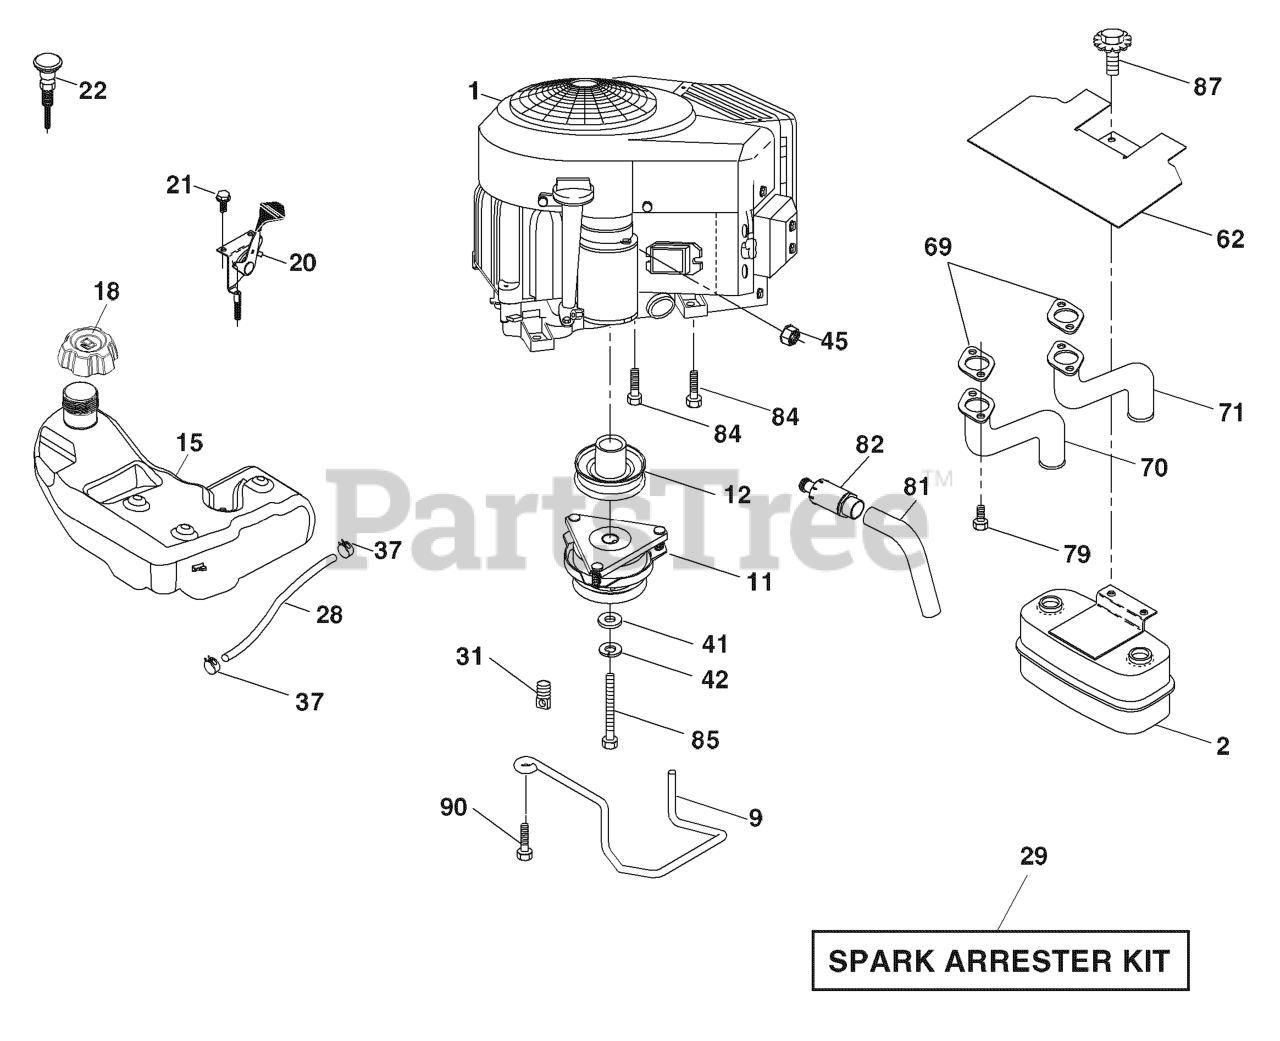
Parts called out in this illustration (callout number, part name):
2	MUFFLER.TWIN.CYL.LOW.TONE
9	KEEPER.BELT.ENGINE.4.2
11	CLUTCH.ELECTRIC.LT.48"*
12	PULLEY.ENGINE.TUFFTORQ
15	TANK.FUEL.4GAL
18	CAP.FUEL.TANK.3"GREY
20	THROTTLE CABLE
21	SCREW.#10 X 0.750.BOS
22	CONTROL.CHOKE.ERGO.PUSH-IN.BLA
28	LINE.FUEL.64"REAR.EMIS
29	KIT.SPARK ARRESTOR 794945 B&S
37	HOSE CLAMP
42	LOCKWASHER
45	NUT
62	RP SHIELD HEAT MUFFLER
69	GASKET.MUFF 806237 NOW 806425
70	EXHAUST.TUBE.MUFFLR.LH.VANG
71	EXHAUST.TUBE.MUFFLR.RH.VANG
79	SCREW.TUBE.MUFFLER.VANGUARD
81	TUBE, DRAIN OIL ASM.
82	PLUG DRAIN OIL EASY
84	SCREW.3/8-16
85	BOLT HEX 7/16-20X4-1/4"
87	BOLT.5/16-18UNCX3/4 W/SEMS.BLK
90	SCREW 3/8-16X1
